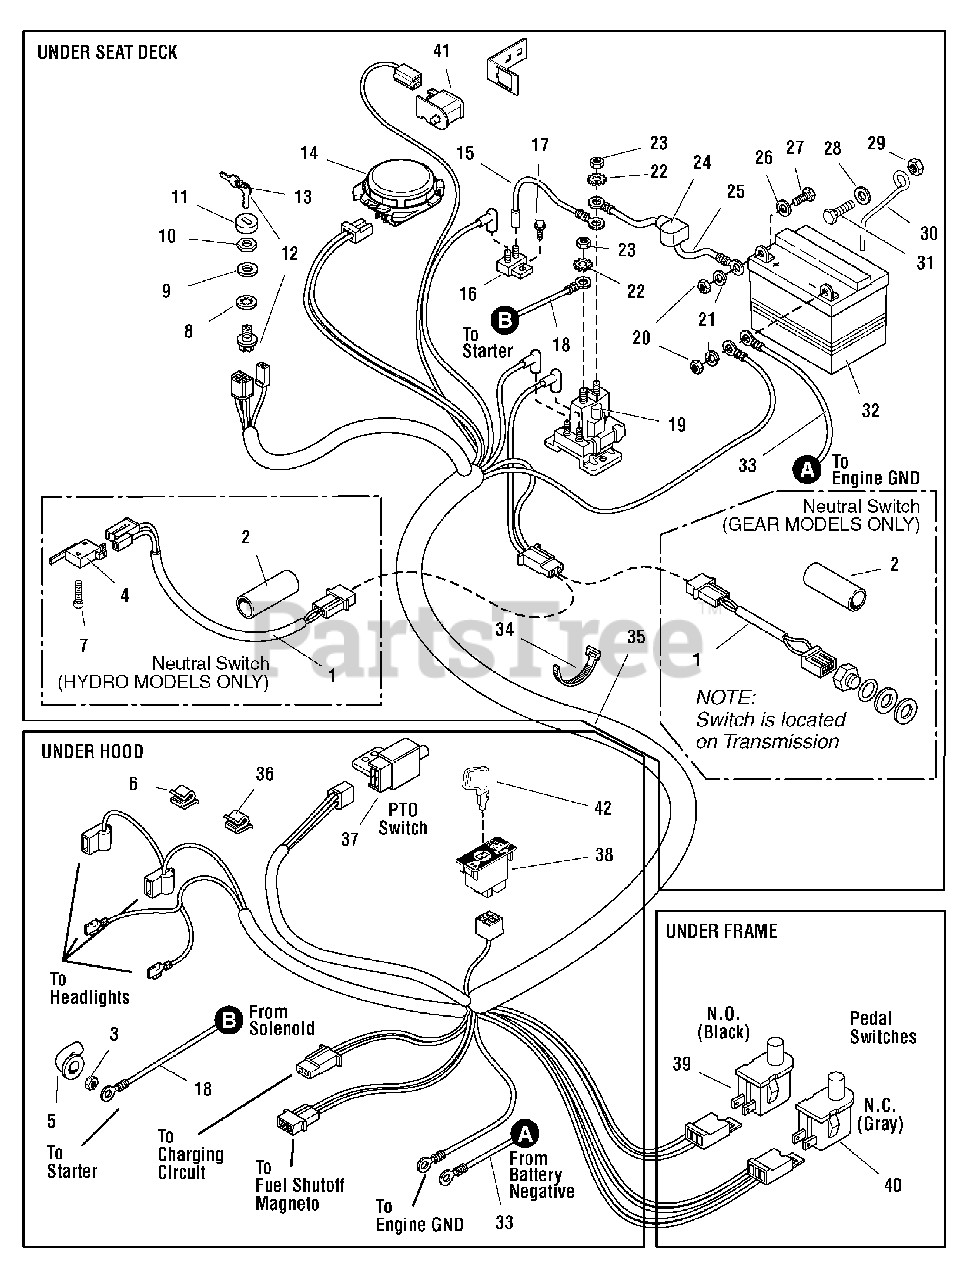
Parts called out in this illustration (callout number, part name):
1	WIRE ASSEMBLY, Neutral Switch (Hydro Models)
1	WIRE ASSEMBLY, Neutral Switch (Gear Models)
2	TUBE, Shrink
3	NUT, Hex Flange, Whiz Lock, 1/4-20
4	SWITCH, Neutral Safety
5	COVER, Terminal
6	CLIP, Tinnerman
7	CAPSCREW, Round Head, Phillips, #4 - 40 x 3/4
8	LOCKWASHER, Internal Tooth, 5/8
9	WASHER, 5/8
10	NUT, Hex, Flange, 5/8-32
11	COVER, Ignition
12	SWITCH, Ignition, 6-Pole (Includes Ref. 8, 9, 10, 11 & 13)
13	IGNITION KEY (Set of 2)
14	SWITCH, Seat
15	WIRE ASSEMBLY
16	CIRCUIT BREAKER
17	CAPSCREW, Taptite Hex Washer Head, 1/4-20 x 5/8
18	CABLE, # 6 x 42-1/2 long (Solenoid to Starter)
19	SOLENOID
20	NUT, Hex, 1/4-20
21	LOCKWASHER, 1/4
22	LOCKWASHER, External Tooth, 5/16
23	NUT, Hex, 5/16-24 NF
24	BOOT, Insulator
25	CABLE, #6 x 10 Long, with 2 Ring Terminals
26	WASHER, Plain, 1/4
27	CAPSCREW, Hex Head, 1/4-20 x 3/4
28	WASHER, Plain, 5/16
29	NUT, Hex Nylon Lock, 5/16-18
30	ROD, Battery Hold Down
31	CAPSCREW, Hex Head, 5/16-18 x 3/4
33	CABLE, # 6 x 52-1/2 long (Battery to Ground)
34	TIE-SELF LOCKING (Qty 2 on Gear Models)
35	HARNESS, Wiring (G & H/C)
35	HARNESS, Wiring (Hydro)
35	HARNESS, Wiring (H/C w/Elec Clutch)
37	SWITCH, Neutral Start
38	SWITCH, RMO Module Only
39	SWITCH, Pedal, N.O., Black
40	SWITCH, Pedal, N.C., Gray
42	KEY, RMO Module, Plastic
